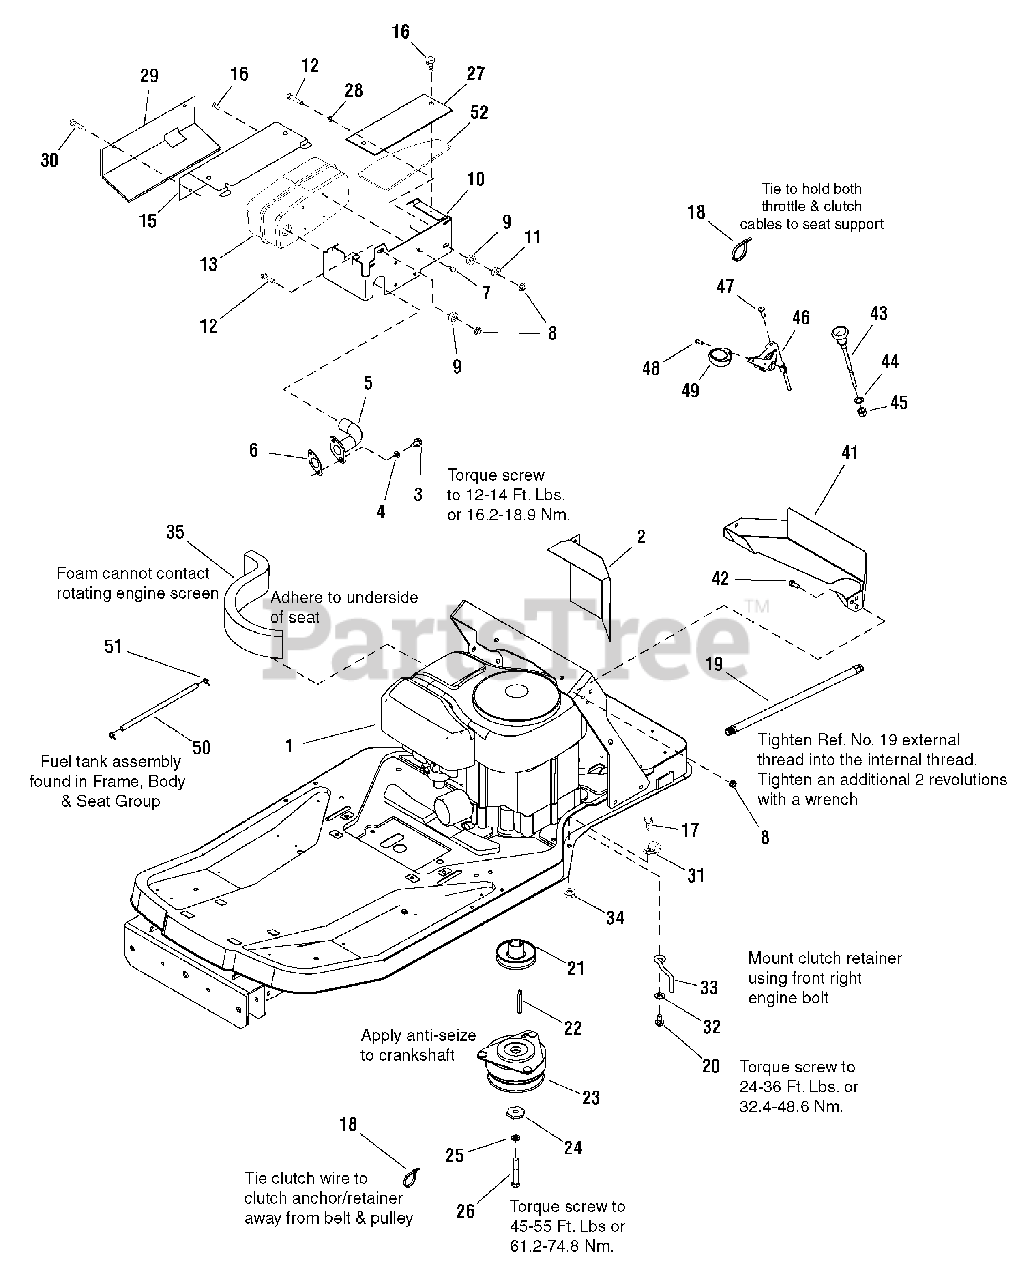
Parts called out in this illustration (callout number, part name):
1	* ENGINE, 18.5 HP, Intek
1	* ENGINE, 18.5 HP, Briggs & Stratton, Els-Calif.
2	HEAT SHIELD, Inner
3	CAPSCREW, Hex Head, 5/16-18 x 3/4, GR8
4	LOCKWASHER, Spring 5/16" Black
5	WELDMENT, Exhaust Pipe
6	GASKET, Exhaust B&S
7	SCREW, Hex Whiz Lock, Flange, 1/4-20 x 5/8
8	NUT, Hex Flange Lock, Large, 5/16-18
9	SPACER (.390 x .900 x .70) YZ
10	BRACKET, Muffler/Heat Shield
11	SPACER, .390 I.D. x .90 O.D. x .34 Long, Powdered Metal
12	CAPSCREW, Hex Head, 5/16-18 x 1-3/4, G5
13	MUFFLER ASSEMBLY, Single
15	HEAT SHIELD, Outer Single
16	CAPSCREW, Hex Washer Head, Self Tap, #10 x 1/2
17	CAPSCREW, Hex Flange Lock, 5/16-18 x 3/4
18	TIE, Self Locking 3-5/8" Long
19	HOSE, Oil Drain, 16-1/2" Long
20	CAPSCREW, Hex Washer Head, Taptite, 3/8-16 x 1-1/4
21	PULLEY ASSEMBLY, Engine
22	KEY, .250 Square x .91 Long Parallel
23	ELECTRIC CLUTCH, Ogura MA-GT-SN11S
24	WASHER, Hex, .453 I.D. x 1-1/2"
25	LOCKWASHER, Spring, .438
26	CAPSCREW, Hex Head Cap, 7/16-20 x 2-3/4, GR5, Black
27	HEAT SHIELD
28	WASHER, 5/16" (.34 I.D. x 3/4" O.D.)
29	HEAT SHIELD
31	CLIP, Harness, 5/8"
32	WASHER, 3/8", (.41 I.D. x .87 O.D. x .08 Thick)
33	RETAINER, Clutch
34	NUT, 5/16-18 Hex Whiz Lock Flange
35	SEAL, Foam Air Duct, 1 x 2-1/2", 12" Long
41	AIR DUCT, Inlet
42	SCREW, 5/16-18 x 3/4" Hex Head Cap, Black
43	CABLE, Choke, 54"
44	WASHER, 3/8" Internal Tooth Lock
45	NUT, 3/8-24 Hex
46	CONTROL, Throttle B&S Intek 16 HP Single
47	SCREW, Pan Head, Taptite Torx, 1/4-20 x 5/8
48	SCREW, Pan Head Taptite Combo, #10-16 x 3/4
49	KNOB, Throttle, Red
50	HOSE, Fuel, 1/4" I.D. x 19-1/2" Low Perm
51	CLAMP, Fuel Hose
52	INSULATION, Foam
